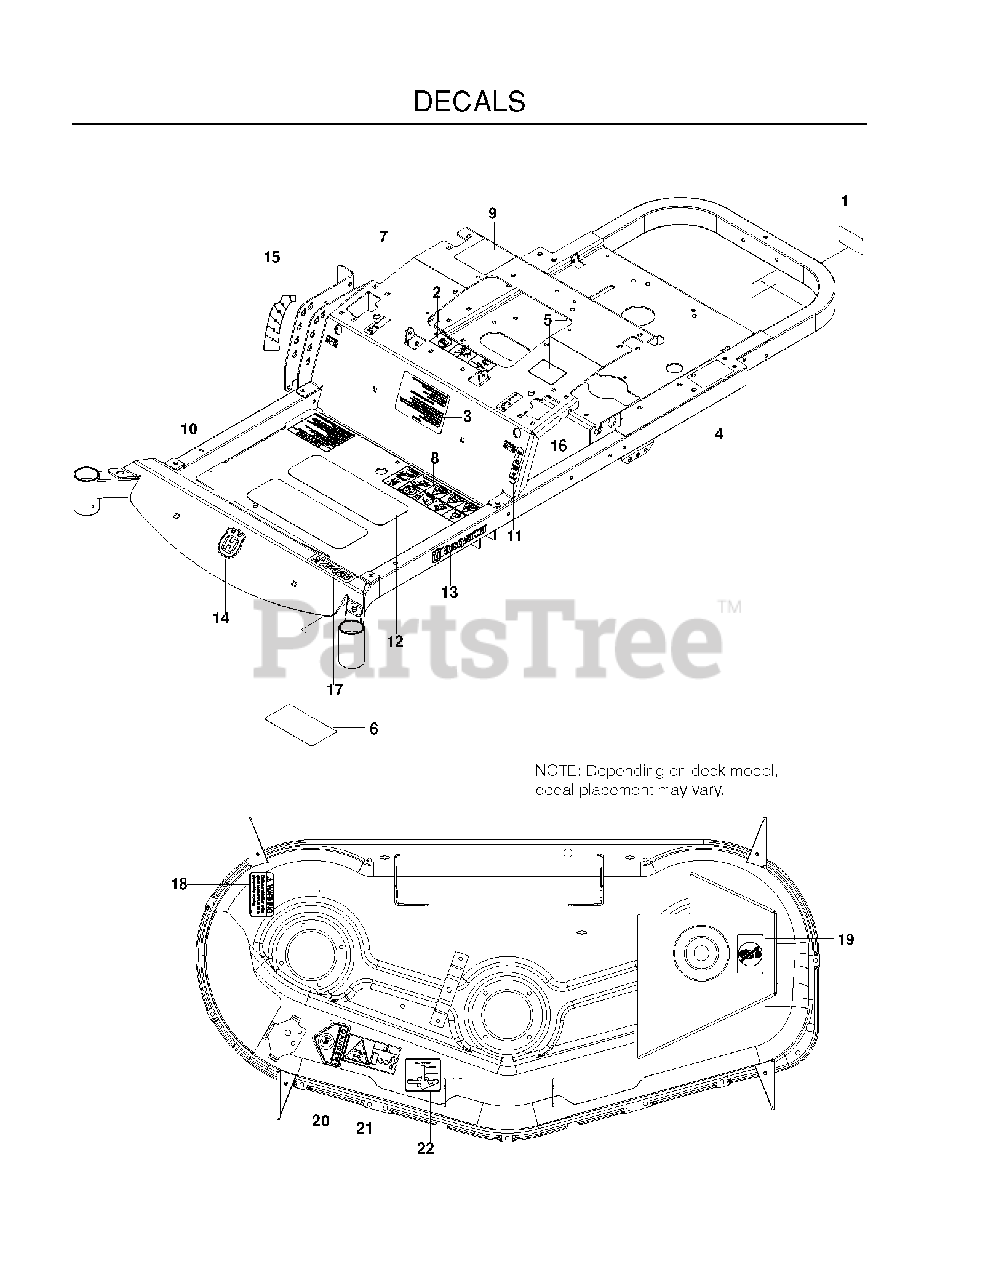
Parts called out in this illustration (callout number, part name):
1	DECAL, PROP. 65
2	EURO DECAL-BATTERY WARNIN6
3	DECAL, START
4	DECAL, DO NOT TOW
5	DECAL, EXITING MOWER
6	DECAL, SERVICE
7	DECAL, MOTION CONTROL
8	DECAL, SAFETY WARNING
9	DECAL, CUSTOMER RESPNSIBILITY
10	DECAL, WARNING
11	DECAL, PARK BRAKE
12	ANTI-SKID PAD
13	DECAL.HOOD.LOGO.ORANGE.HUSQVAR
14	DECAL, CROWN H 70MM
15	DECAL, HEIGHT
16	DECAL, F.S.T.
17	DECAL, RZ4219
18	DECAL, CAUTION
19	DECAL, NO STEP
20	DECAL, CPSC
21	DECAL, EURO SEVERING
22	DECAL, BELT ROUTING
